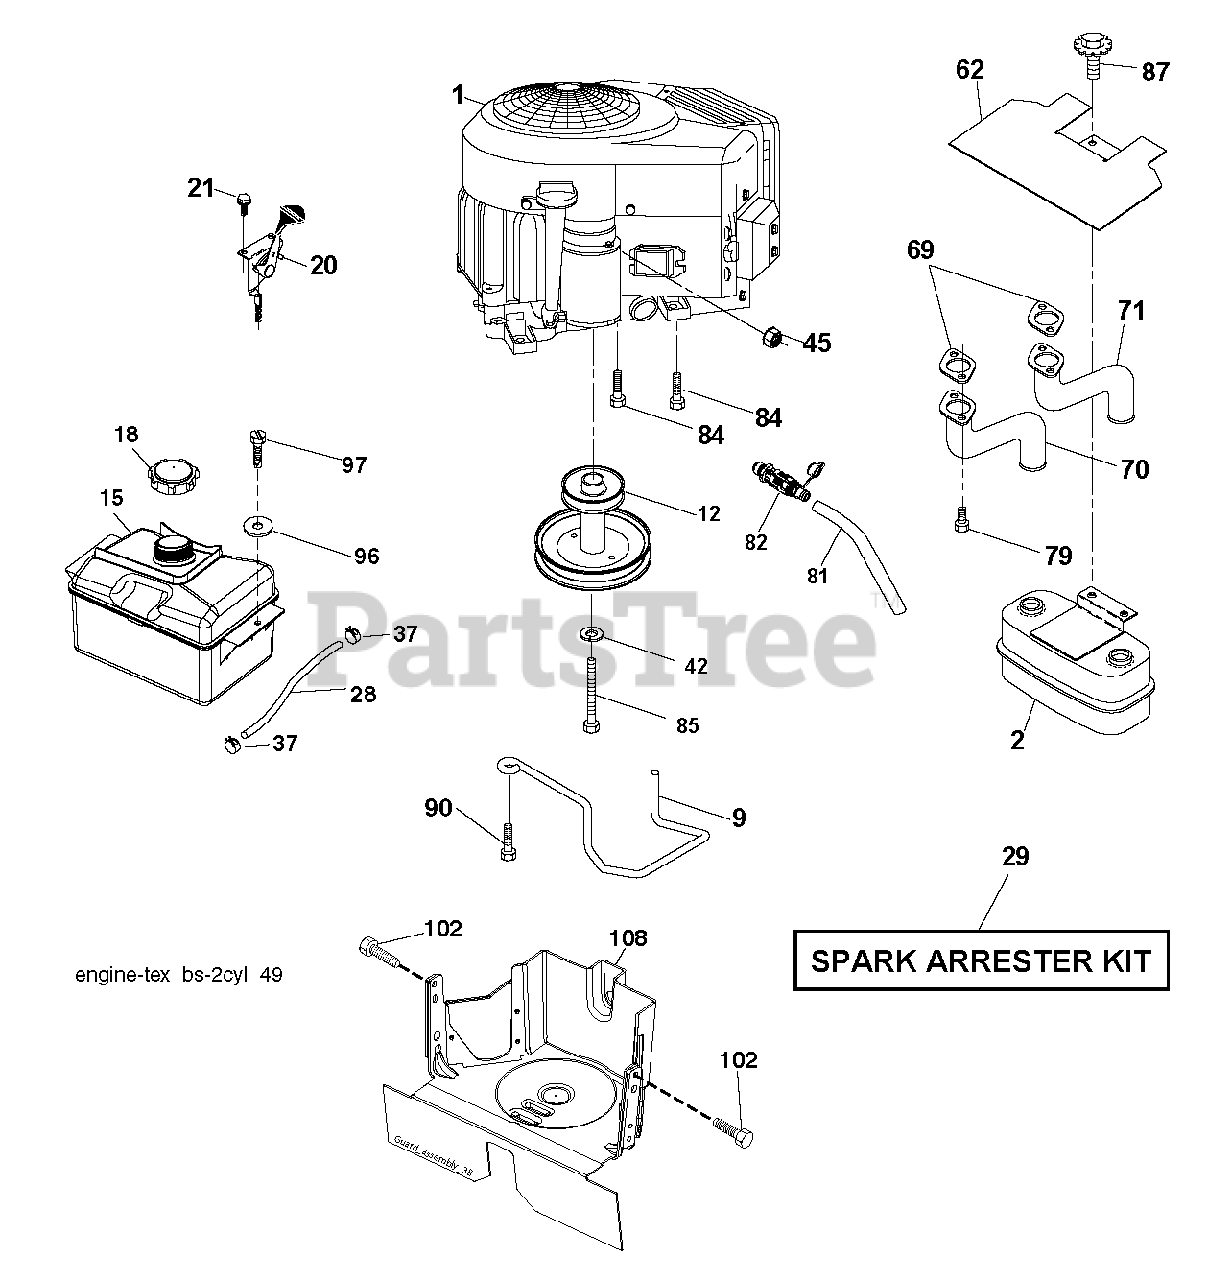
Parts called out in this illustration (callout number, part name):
2	MUFFLER.TWIN.CYL.LOW.TONE
9	Belt Keeper, 4 25"2 Blt 431
12	PULLY ENGINE
15	TANK.ASM.FRNT.2.GA.DAPCO.E10
18	CAP ASM.FUEL.2.25"FR.
20	CONTROL.TH/CK.COBRA.B&S.TWN.
21	SCREW.#10 X 0.750.BOS THREAD
28	LINE.FUEL.20
29	ARRESTER SPARK (OPTIONAL)
37	HOSE CLAMP
42	LOCKWASHER
45	NUT
62	SHIELD.HEAT.MUFFLER
69	GASKET.MUFFLER
70	TUBE MANIFOLD LH
71	EXHAUST TUBE RH
79	SCREW.SOCKET.HEAD.5/16-18
81	TUBE, DRAIN OIL ASM.
82	VALUE.OIL.DRAIN
84	SCREW.3/8-16
85	BOLT HEX 7/16-20X4-1/4"
87	BOLT, 5/16-18 X 1 3/4
90	SCREW 3/8-16X1
97	SCREW HEXWSHR 1/4-20X3/4
102	SCREW 5/16-18X1
